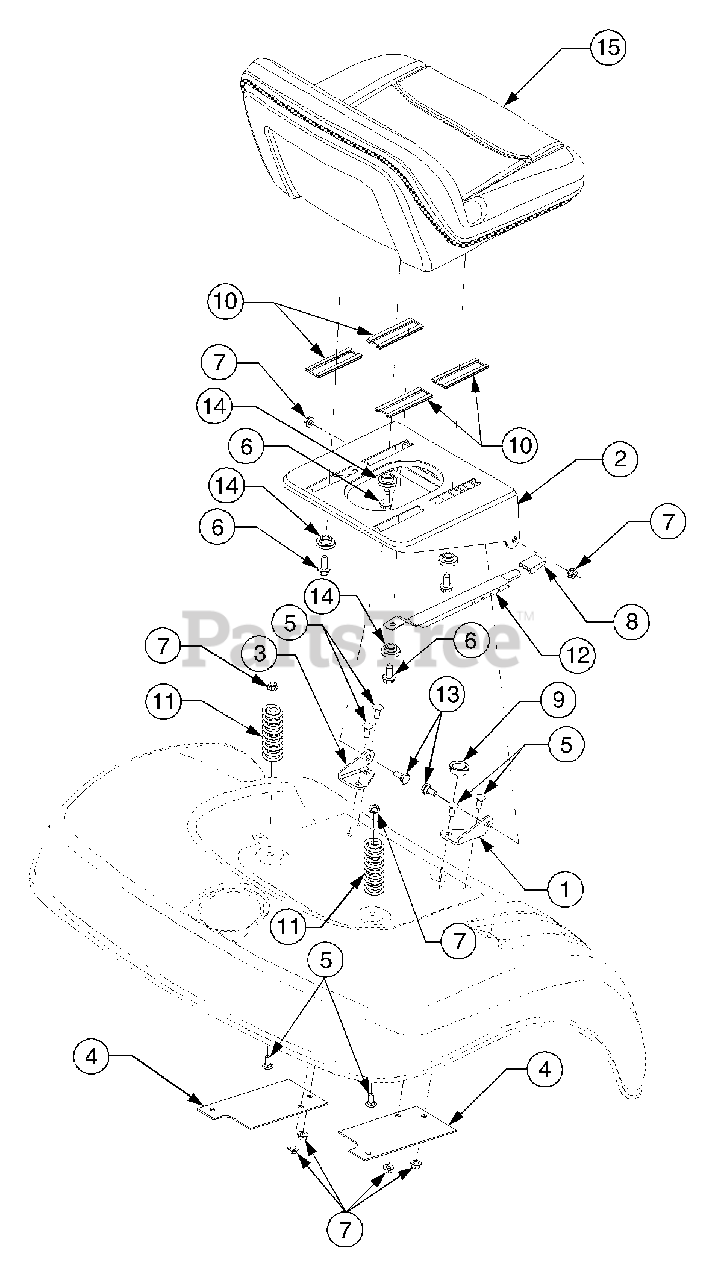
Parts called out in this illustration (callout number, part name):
1	Bracket, RH Seat Pivot
2	Graphic, Seat Adjuster
3	Bracket, LH Seat Pivot
4	Bracket, Fender Reinforcement
5	Bolt, Carriage, 5/16-18 x .75
6	Screw, Hx Wash. Hd. Tapp., 5/16-18 x .75
7	Nut, Hex Flange Lock, 5/16-18
8	Knob, Seat Adjuster
9	Bushing, Snap, 7/8 ID
10	Slide, Seat
11	Spring, Comp, 1.9 OD x 2.4
12	Spring, Index
13	Bolt, Shoulder
14	Spacer, Shoulder
15	Seat, Mid Back
